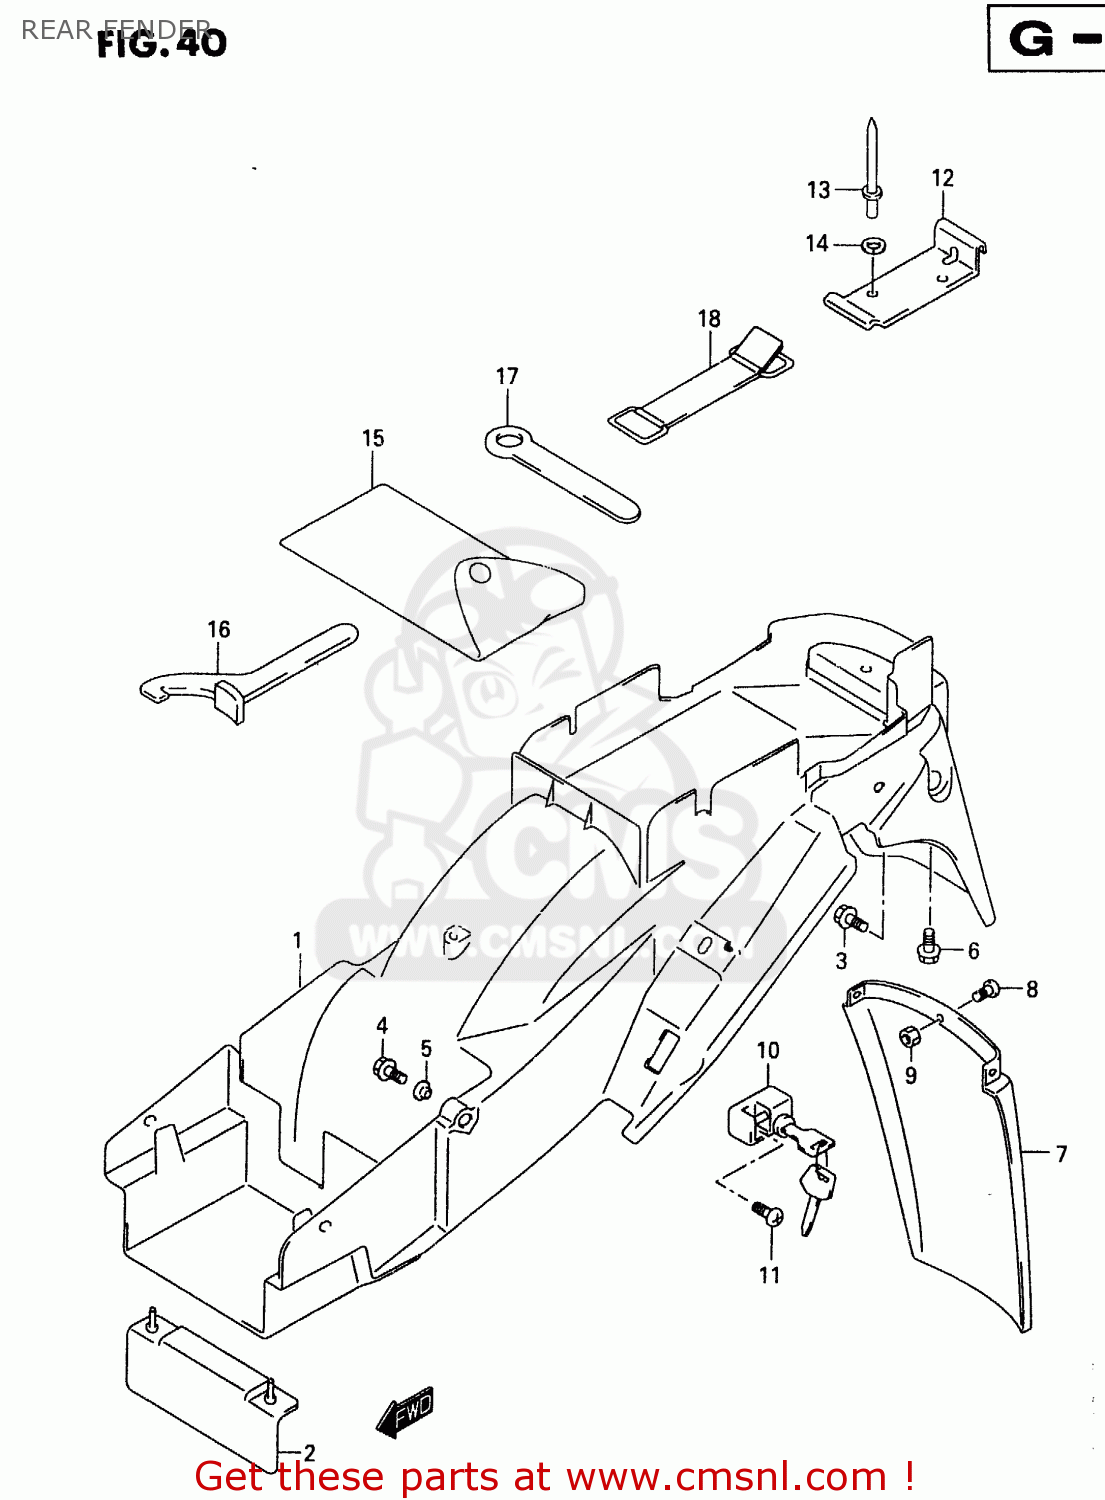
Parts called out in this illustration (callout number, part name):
1	FENDER,RR
2	MUDGUARD,RR FENDER FR
3	BOLT(6X16)
4	BOLT
5	WASHER
6	BOLT 6X16
7	EXTENSION,RR FENDER
8	SCREW
9	NUT
10	LOCK SET,HELMET
11	SCREW(6X14)
12	HOLDER,TOOL
13	RIVET
14	WASHER
15	TOOL ASSY
16	CLAMP
17	SPANNER,HEXAGON
18	BAND,TOOL
